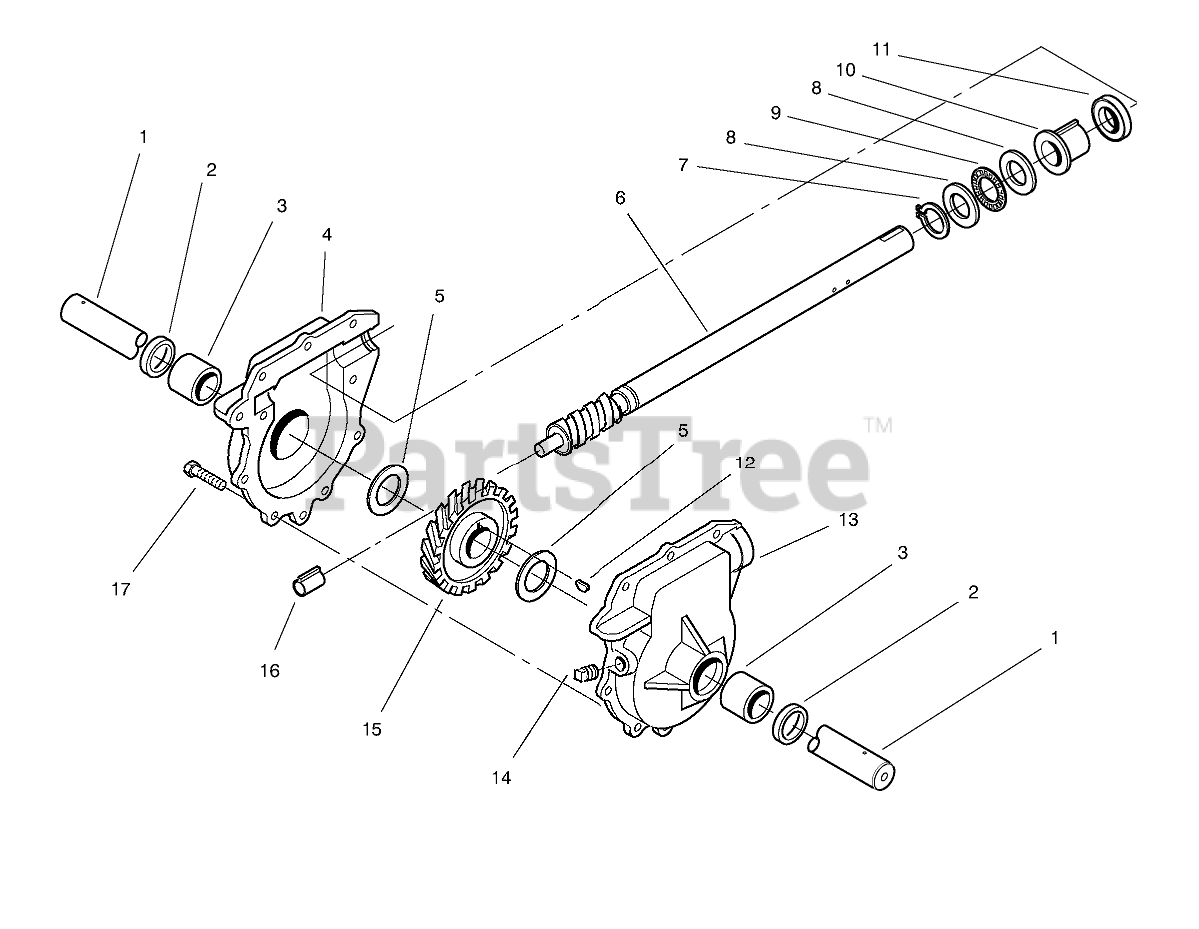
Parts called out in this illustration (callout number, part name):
1	SHAFT-AUGER
2	SEAL-OIL
3	BUSHING
4	Gearcase Assembly-R.H. (Incl. Ref. # 2-3)
5	WASHER-THRUST
6	SHAFT-IMPELLER
7	RING-RETAINING, Ext
8	WASHER-THRUST
9	BEARING-THRUST
10	BUSHING-INPUT
11	SEAL-OIL
12	KEY-WOODRUFF
13	Gearcase Assembly-L.H. (Incl. Ref. # 2-3, & 17)
14	PLUG-PIPE, SQH
15	GEAR-HELICAL
16	BUSHING-WORM
17	SCREW-HWH
